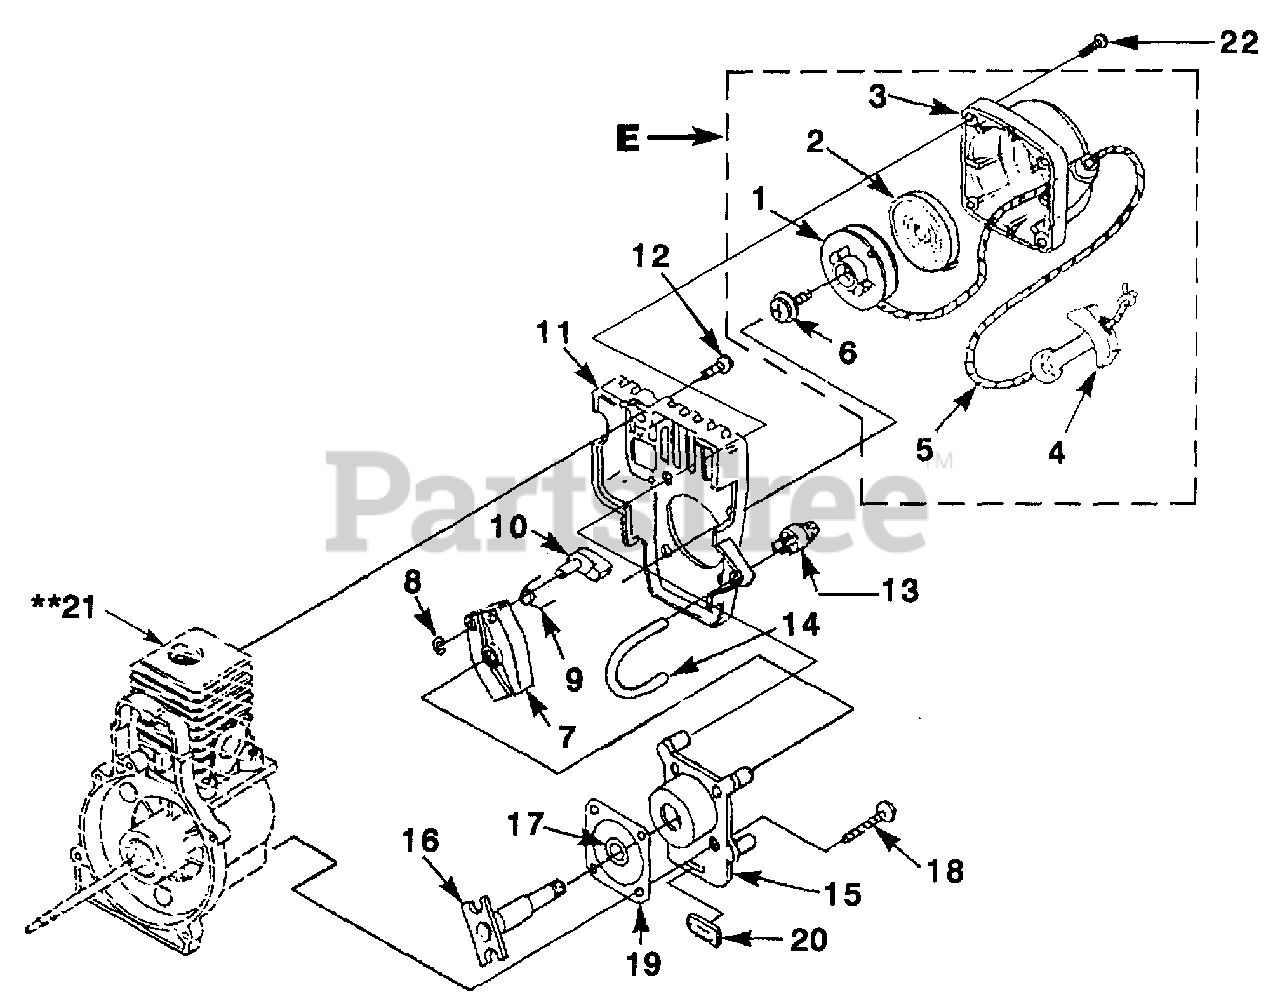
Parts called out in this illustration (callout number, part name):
1	PULLEY-Starter
2	SPRING-Recoil
3	HOUSING-Starter
4	GRIP-Starter
5	ROPE-Starter
6	SCREW-Set
7	CUP-Starter
8	RETAINING RING
9	SPRING-Starter
10	PAWL-Starter
11	COWLING-Engine
12	SCREW-Thread Forming (#10 x 1/2")
13	BULB-Air Purge
14	RUBBER TUBING (8")
15	CRANKCASE COVER
16	SHAFT-Starter
18	SCREW-Thread Form. (10-24 x 3/4")
19	GASKET-Crankcase
20	BUMPER-Rubber
21	SHORT BLOCK
22	SCREW-Taptite, T-25 Torx (10-24 x 3/4")
E	STARTER-Complete
